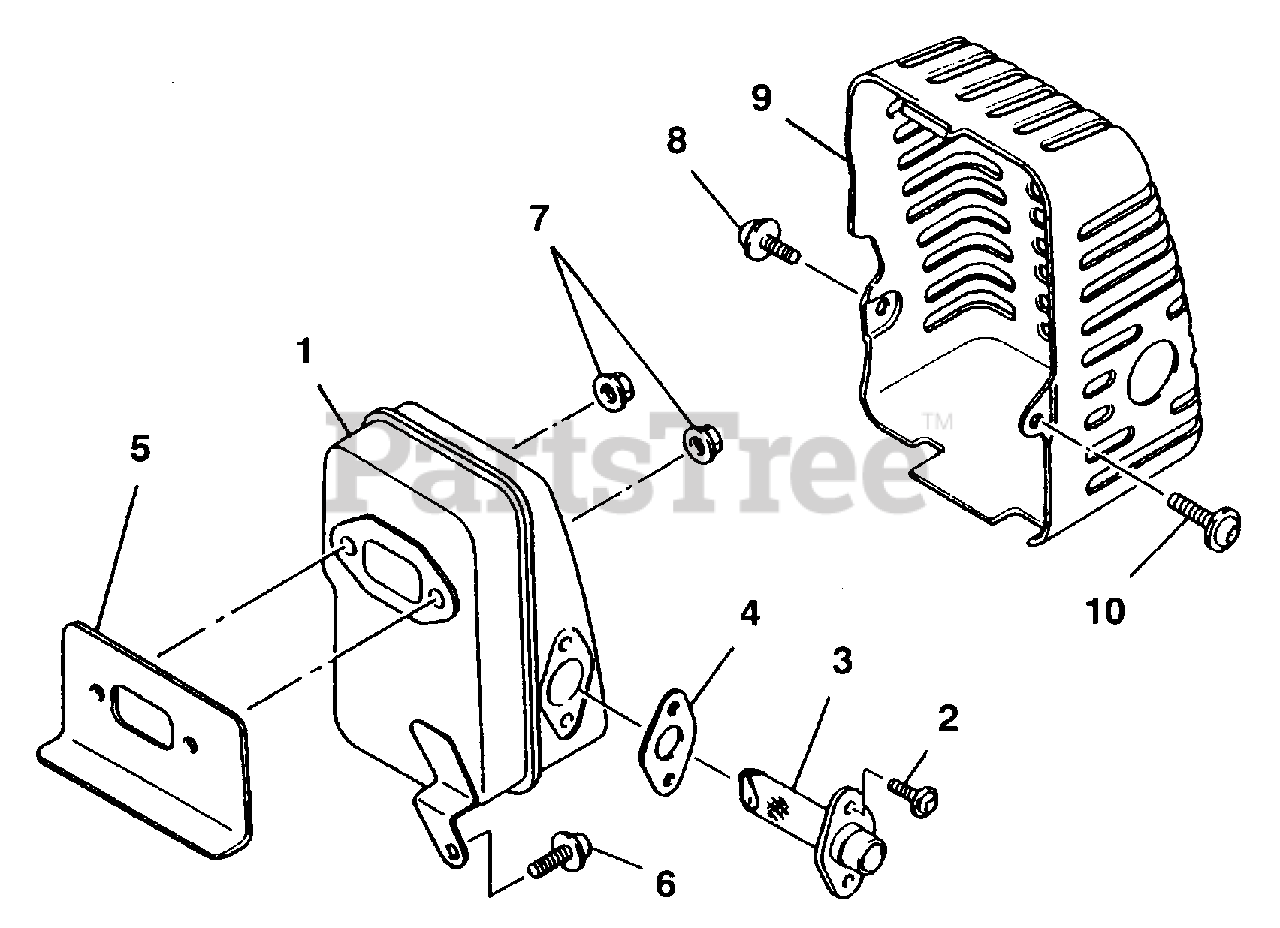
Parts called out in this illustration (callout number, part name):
1	Muffler Assembly
2	Screw & Washer
3	Tail Pipe
4	Gasket, Tail Pipe
5	Gasket, Muffler
6	Screw & Washer
7	Nut, Flange
8	Screw & Washer
9	Cover, Muffler
10	Screw & Washer
